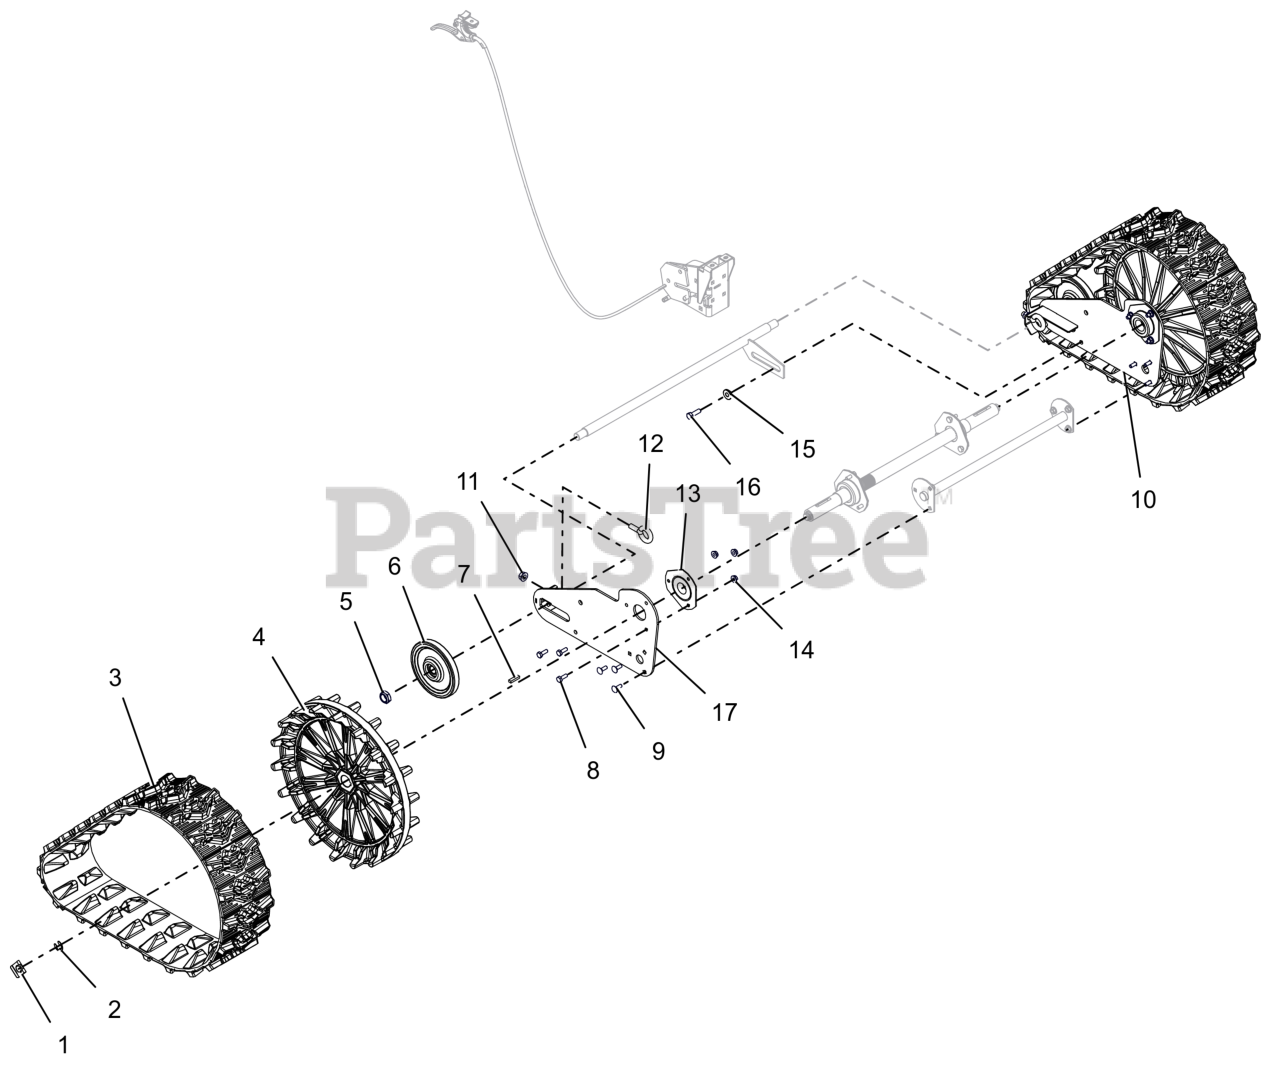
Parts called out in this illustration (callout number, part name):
1	CLIP, SNAP .625 DIA
2	RG-RTNG-EXT .625X.042
3	TRACK, RUBBER - 22 PITCHES
4	SPROCKET, LARGE TRACK DRIVE
5	NUT, NYL LK .625-18 ZCC
6	WHEEL, BOGIE - SINGLE BEARING
7	KEY-RECT .25X.188X1.00
8	BLT, HEX .25-20X.75 G5 ZCC
9	BLT, RHSN .25-20X.750 G5 ZCC
10	PLATE, SIDE-BWT LH WLDMT
11	NUT-LK-CTR-FLG .375-16 GF ZCC
12	BLT-EYE .375-16X.880 YWZC
13	BRG-FLG 1.003/1.000 3 BOLT
14	NUT-LK-TOP-FLG .250-20 GF ZCC
15	BSHG-FLG .325X.499X.3X.875
16	BLT,HEX .31-18X1.00 G5 ZCC
17	PLATE, SIDE-BWT RH WLDMT
